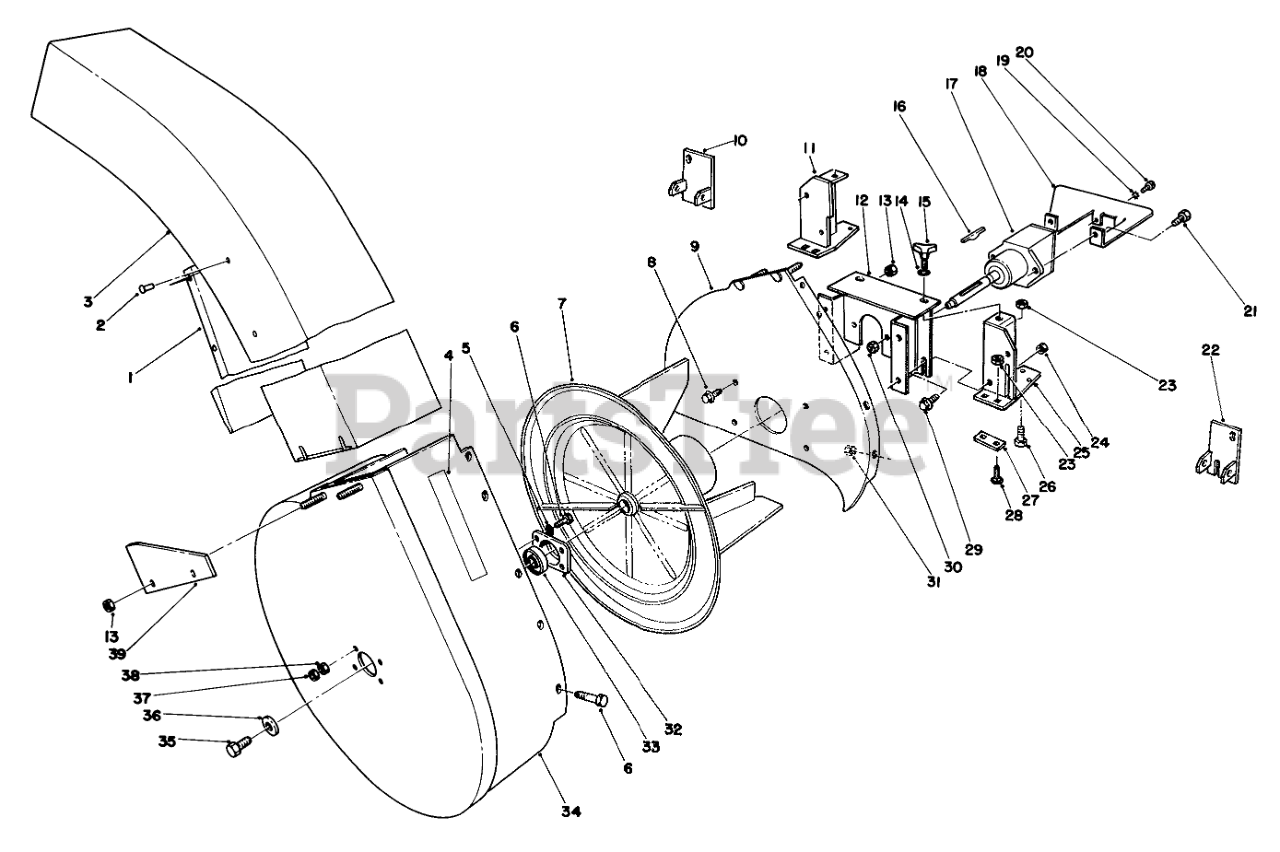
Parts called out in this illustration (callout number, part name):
1	Deflector-Chute
3	Chute Assembly (Incl. Ref. #1 & 2)
4	Decal-Waming
5	WASHER-LOCK
6	SCREW-HH
7	Impeller
8	SCREW-HHF
9	Mounting Plate
10	Bracket-Deflector L.H.
11	LH BRACKET ASM
12	Blower Mount
13	NUT-LOCK, NI
14	WASHER-FLAT
15	Knob
17	Asm-Gear Box
18	Cover-Gear Box
19	WASHER-LOCK, EXT
21	SCREW-HH
22	Bracket-Deflector R.H.
23	NUT-LOCK, CONE
24	NUT-JAM
25	RH BRACKET ASM
26	SCREW-HH
27	Plate-Bracket
28	BOLT-CARR
29	SCREW-HHF
30	NUT-LOCK, NI
31	NUT-LOCK, NI
32	CUP-BEARING
33	BEARING-BALL
34	Blower Housing
35	CAPSCREW 3/8 16 3/4
36	SPACER
37	NUT-JAM
38	NUT-HEX
39	Bracket
